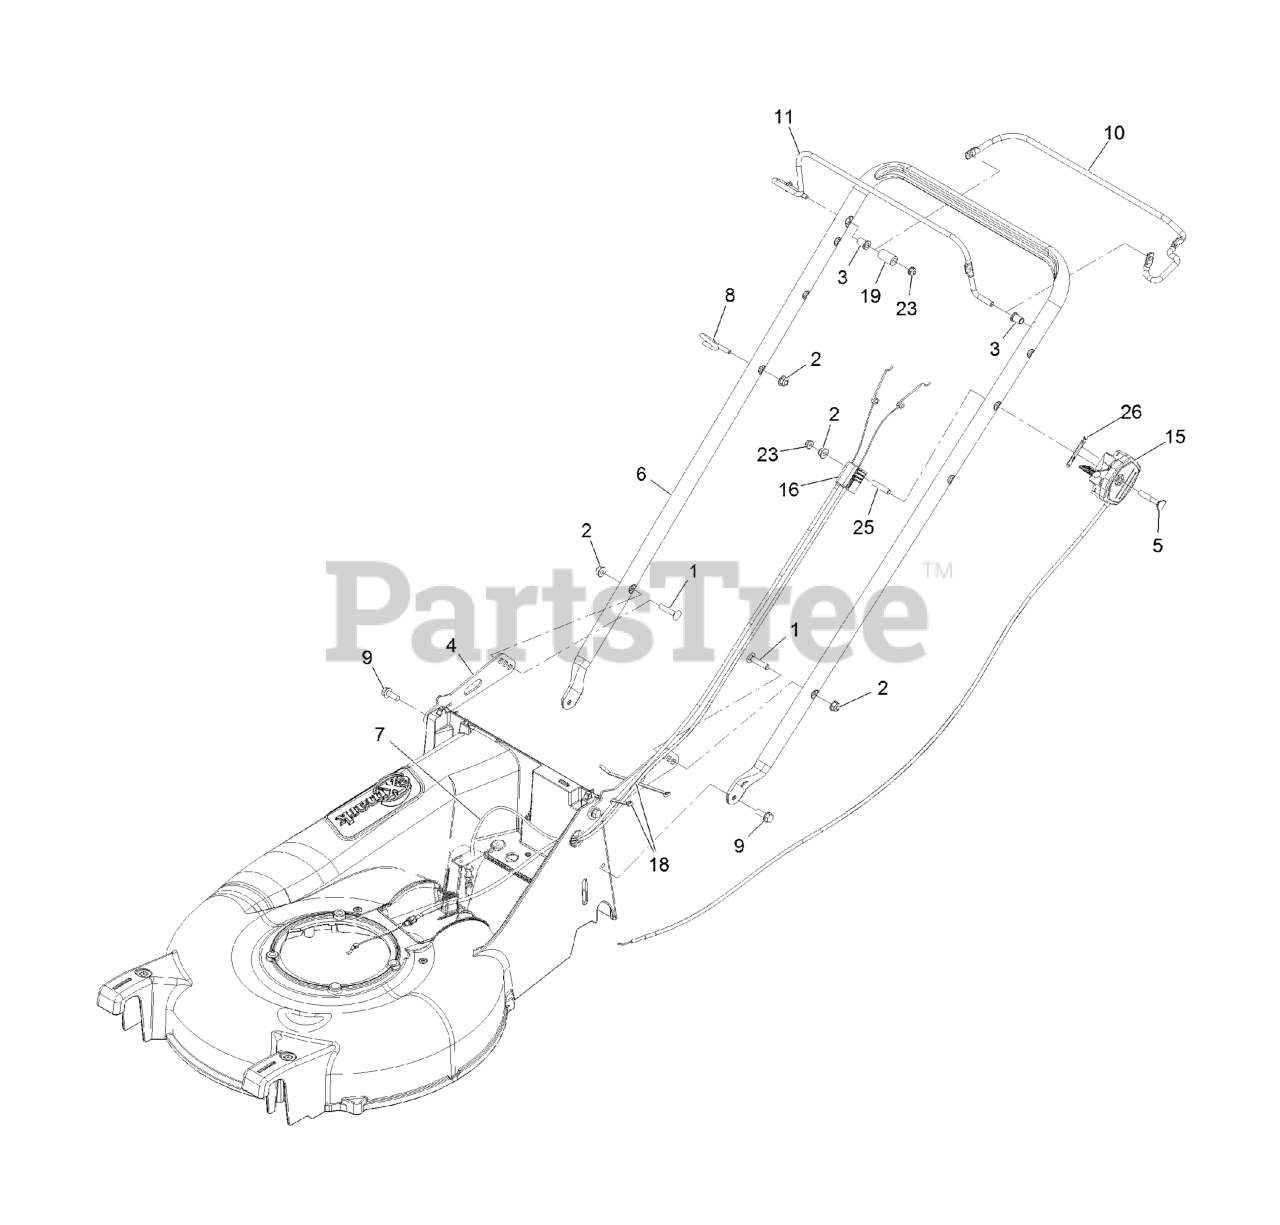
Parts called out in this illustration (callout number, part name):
1	BOLT-CARR
2	NUT-HF, NI
3	BUSHING-HANDLEBAR
4	BRACKET,HANDLEBAR
5	SCREW-HH
6	HANDLEBAR-P21
7	CABLE, DRIVE EC21
8	GUIDE,ROPE
9	SCREW-TAPTITE
10	BAIL-DRIVE COATED
15	CABLE-THROTTLE/CHOKE
16	CABLE-ZONE HONDA
18	TIE-CABLE
25	SPACER-THROTTLE
26	DECAL,THROTTLE/CHOKE
